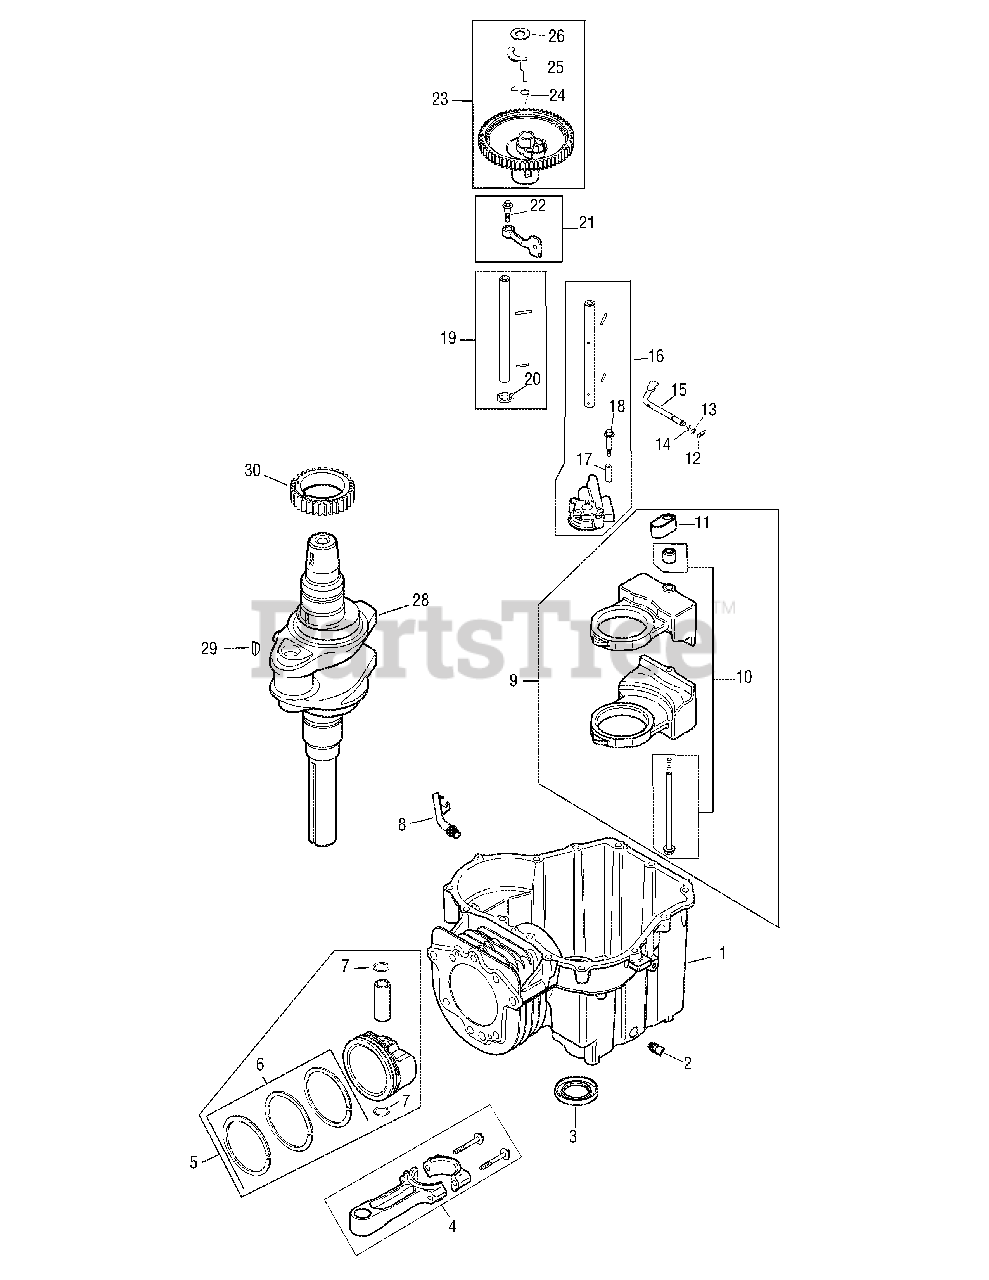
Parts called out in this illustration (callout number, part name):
1	Crankcase, Use Short Block
1	Short Block
2	Plug, sq. hd. pipe 3/8"
3	Seal, oil
4	Rod, connecting
5	Piston w/ Ring Set
6	Ring Set (89 mm)
7	Retainer, piston pin
8	Tube, drainback
9	Kit, balance weight
10	Kit, screw/guide pin
12	Clip, hitch pin
13	Washer, plain
14	Washer, plain
15	Shaft, governor cross
16	Pump assembly, oil
17	Spacer, oil pump screw
18	Screw, oil pump
19	Shaft center, cam - Exhaust
20	Washer, thrust
21	Lever assembly, cam
22	Screw, shoulder
23	Gear assembly, cam
25	Weight, ACR
26	Washer, thrust - ACR
30	Gear, crankshaft
